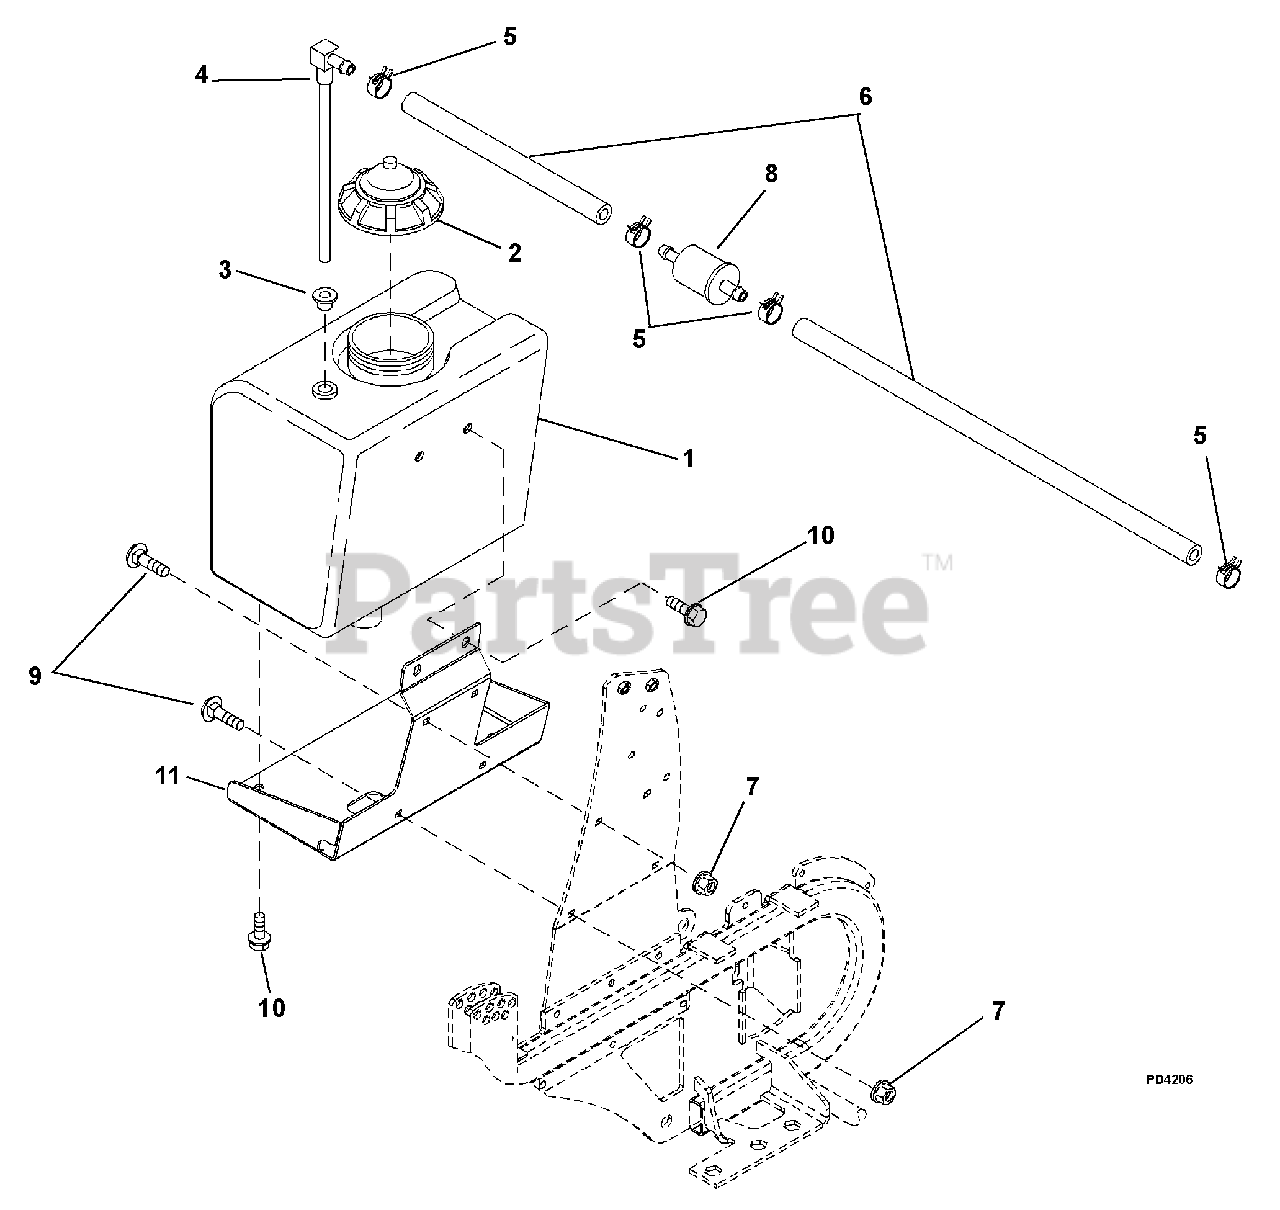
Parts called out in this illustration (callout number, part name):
1	Fuel Tank
2	Cap, Fuel
3	Grommet
4	Fuel Pickup
5	Clamp
6	Hose, 10 FT Service #
7	Nut, Lock, Nylon M10-1.5
8	Filter
9	Carriage Bolt, M10 x 1.5 x 25
10	Bolt, Hex, M8 x 1.25 x 16
11	Bracket, Fuel Tank Mounting
